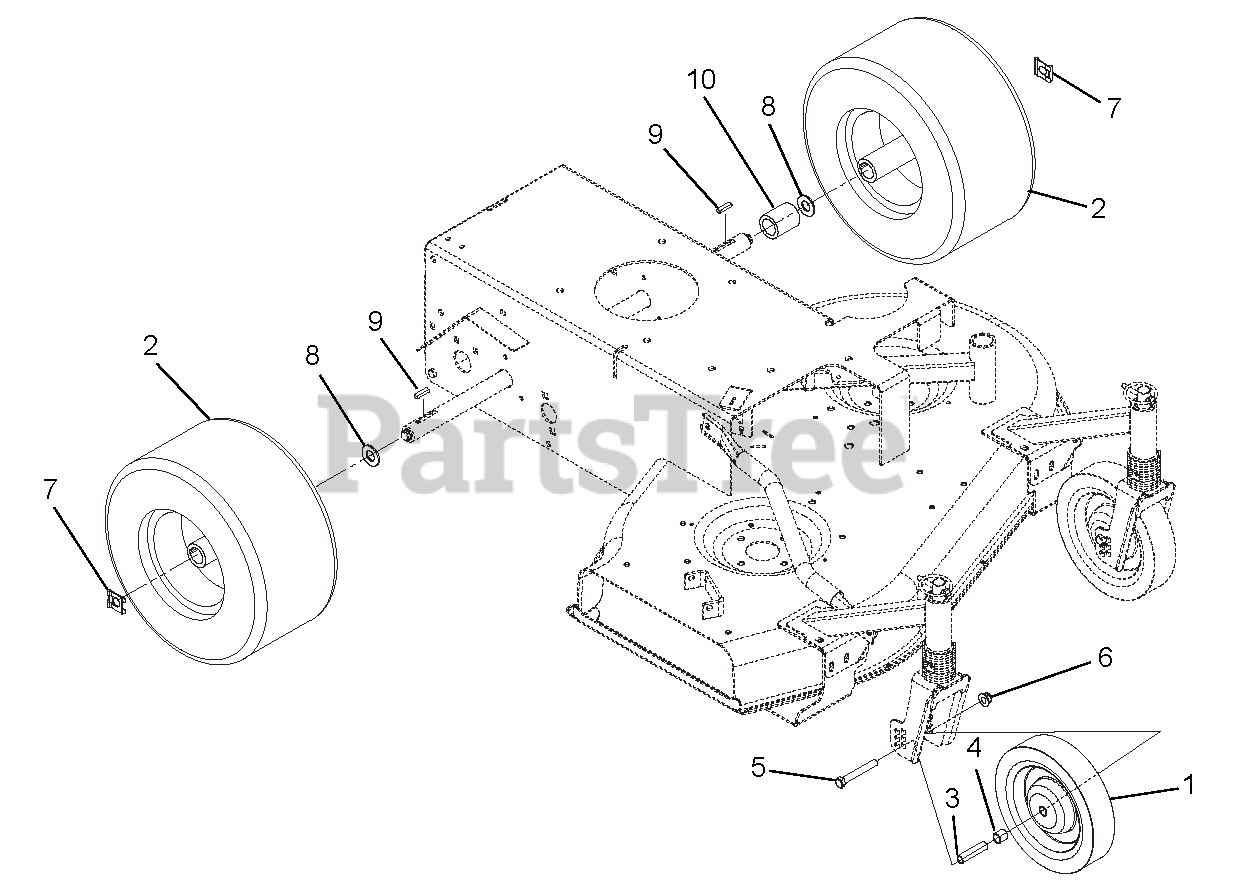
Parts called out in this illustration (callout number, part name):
1	WHEEL, 8.0X1.75X.50 - BALL BRG
2	ASSY, TIRE/WHEEL 6X13
3	SPCR, WHEEL .385X.500X2.00
4	SPACER-WHEEL
5	@BLT-HEX .38-16X2.75 GR5 YWZC
6	@NUT-LK-NYL-FLG .38-16 YWZC
7	CLIP, SNAP .625 DIA
8	@WSHR-FL-STL.656X1.31X.095 YWZ
9	KEY-RECT .25X.188X1.00
10	SPACER, 1.0X1.5X1.57
